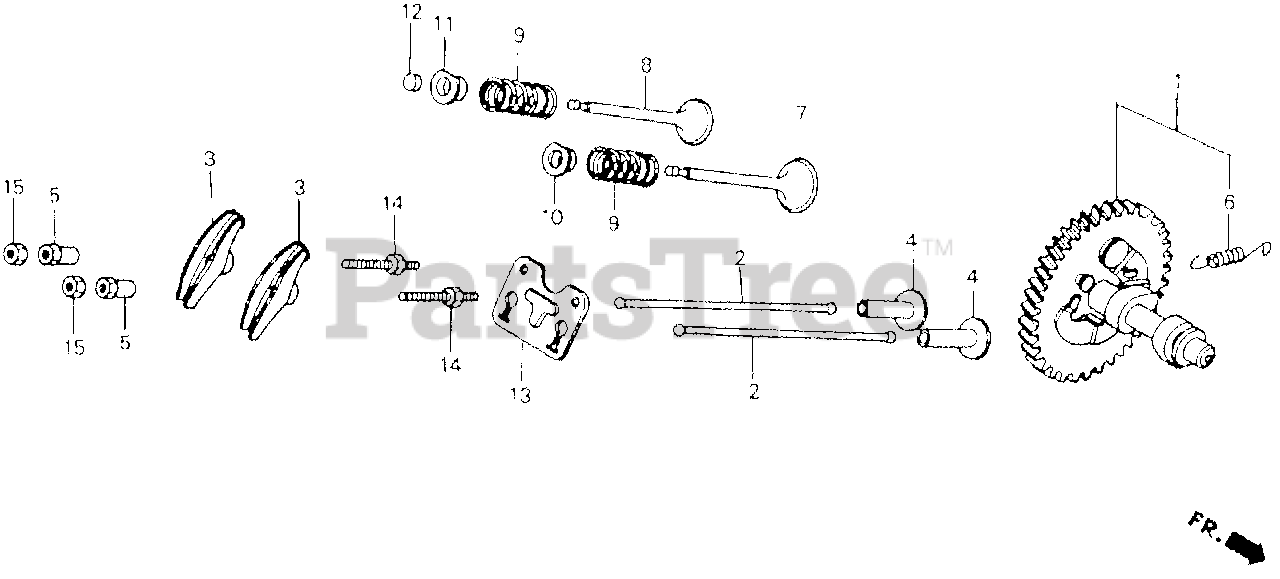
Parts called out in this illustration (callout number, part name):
1	CAMSHAFT ASSY.
2	ROD, PUSH
3	ARM, VALVE ROCKER
4	LIFTER, VALVE
5	PIVOT, ROCKER ARM
6	SPRING, WEIGHT RETURN
7	VALVE, IN.
8	VALVE, EX.
9	SPRING, VALVE
10	RETAINER, IN. VALVE SPRING
11	RETAINER, EX. VALVE SPRING
12	ROTATOR, VALVE
13	PLATE, PUSH ROD GUIDE
14	BOLT, PIVOT (8MM)
15	NUT, PIVOT ADJ.
